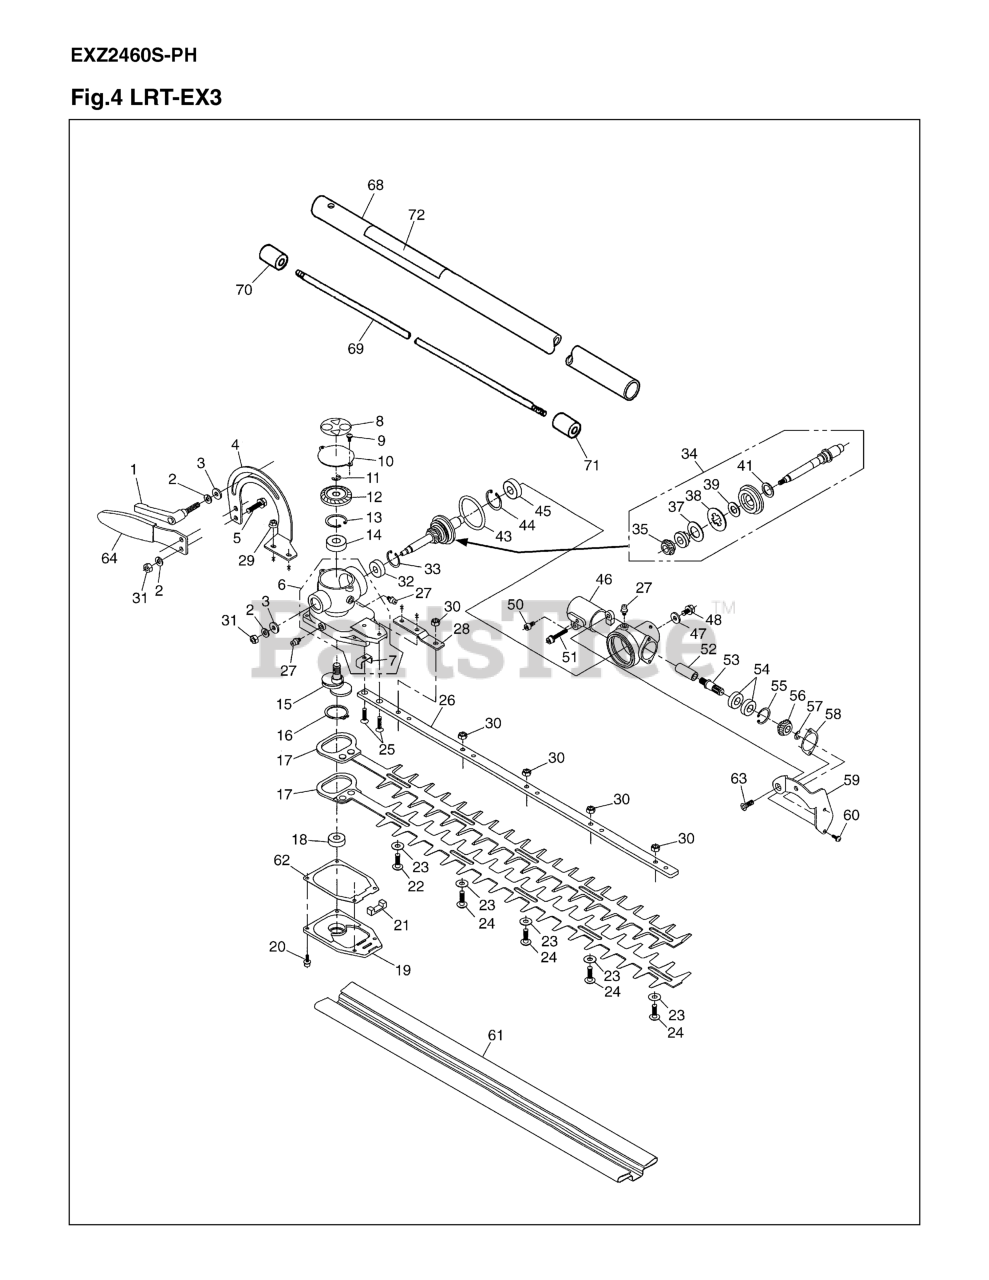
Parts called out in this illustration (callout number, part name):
1	CLAMP LEVER
2	WASHER, M6 x 15
3	WASHER,6x15x2.0(
4	ANGLE ADJUSTER
5	BOLT
6	CASE (A) SET RPL
7	PLATE
8	LABEL
9	SCREW, M4 x 8
10	COVER
11	RING, SNAP
12	GEAR, BEVEL
13	RING,SNAP M26x1.
15	CRANKSHAFT
16	RING, SNAP, M28
18	BEARING
19	COVER
21	FELT
22	SCREW(R3873,3884
23	WASHER RPL 38731
24	SCREW
25	SCREW, M5 x 20
26	GUIDE PLATE
27	FITTING, GREASE
28	PLATE (RPLS 6780
29	NUT, M5
30	NUT, M6
31	NUT, M6 x 5 (RPL
32	BEARING
33	RING, SNAP, M22
34	KIT,SHAFT(R67821
35	GEAR (C)
37	WASHER, SPRING
43	O-RING
44	RING,SNAP M26x1.
46	CASE (B)
47	WASHER,6x15x2.0(
48	BOLT M6x12 (RPLS
50	BOLT, M5 x 12
51	BOLT
52	JOINT (RPLS T307
53	SHAFT, GEAR
54	BEARING
55	RING, SNAP, M22
56	GEAR, BEVEL
57	RING, SNAP
58	PACKING
60	SCREW, M4 x 10 (
61	BLADE COVER
62	GASKET
68	PIPE COMPLETE
70	JOINT, SHAFT (RP
71	SPACER
72	PLATE NAME
